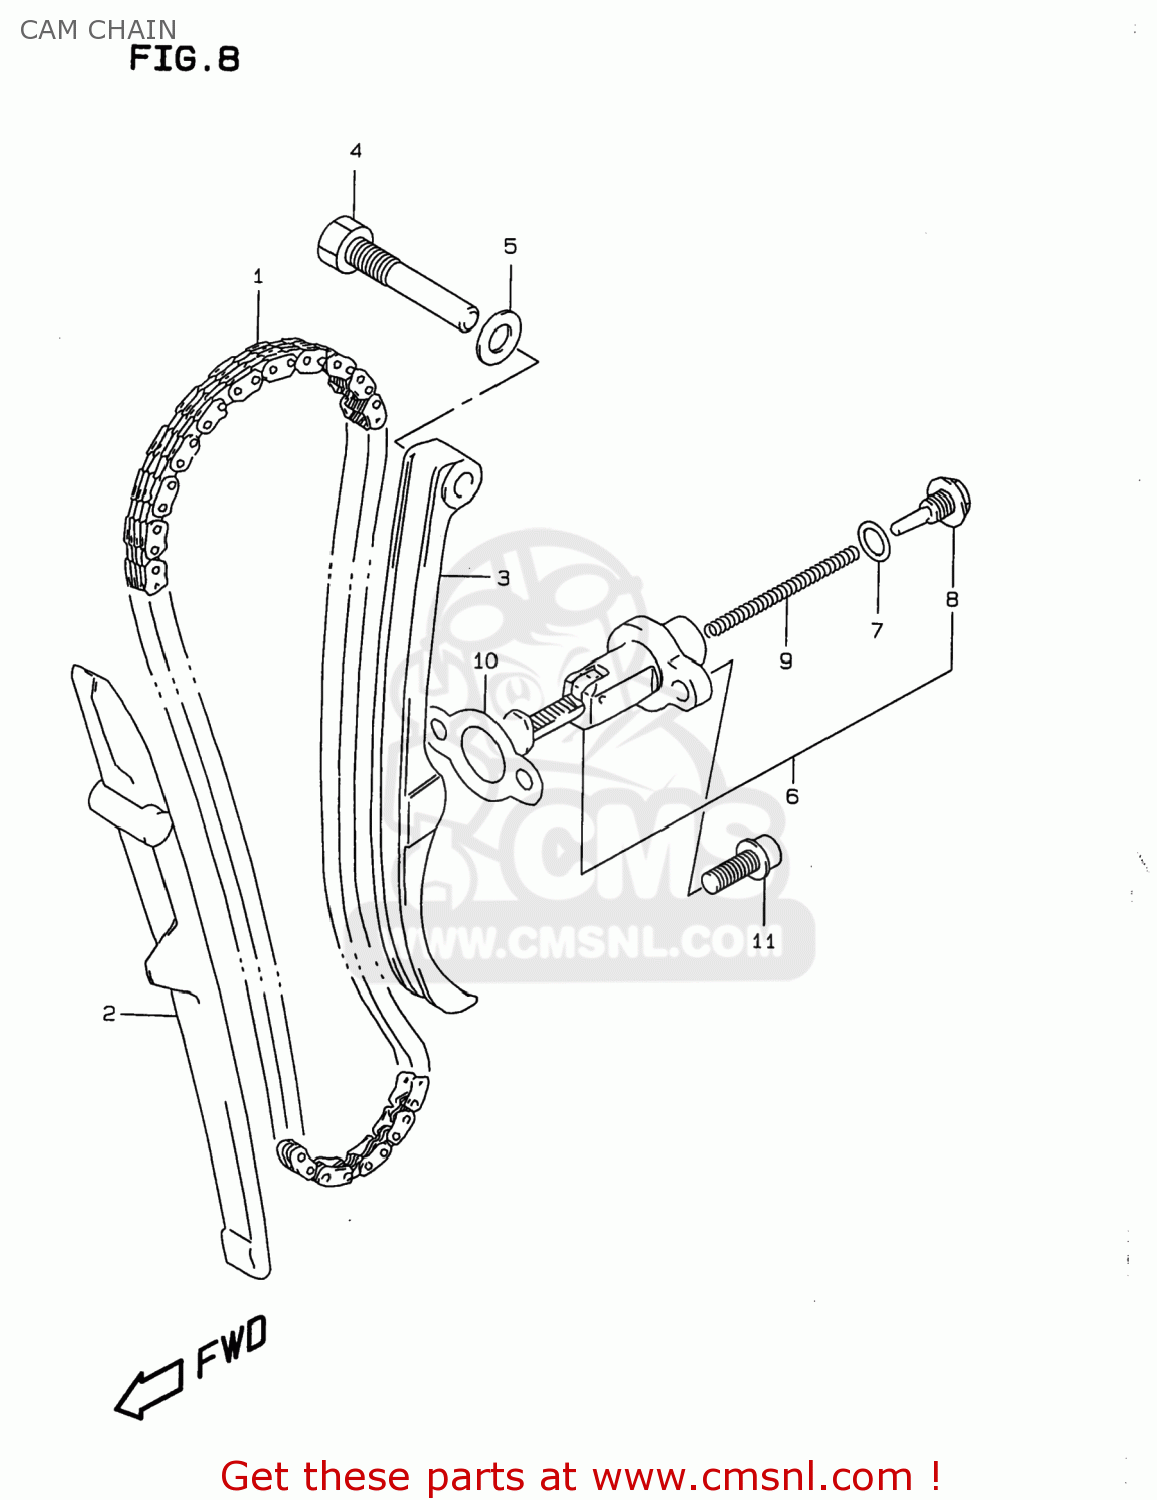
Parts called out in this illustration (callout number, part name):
1	CHAIN,CAMSHAFT DRIVE
2	GUIDE,CAM CHAIN
3	TENSIONER,CAM CHAIN
4	BOLT,CAM CHAIN TENSIONER
5	GASKET 8.2X14X1 (NAS)
6	ADJUSTER ASSY,TENSIONER
7	O RING
8	PLUG,ADJUSTER
9	SPRING
10	GASKET,TENSIONER ADJUSTER (NAS)
11	BOLT
